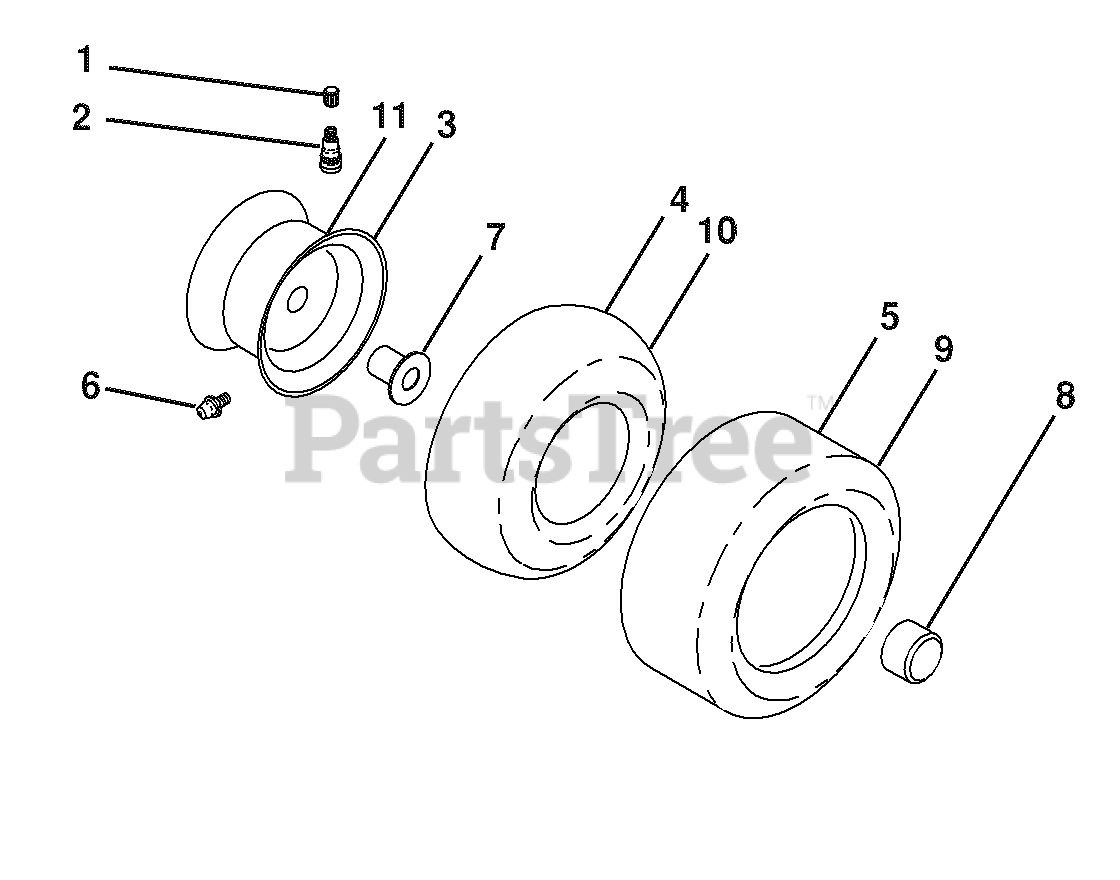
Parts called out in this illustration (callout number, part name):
1	Cap, Valve, Tire
2	Stem, Valve
3	Rim Assembly, Front
4	Tube, Front
5	Tire, Front
6	Fitting, Grease
7	Bearing, Flange
8	Cap, Axle
9	Tire, Rear
10	Tube, Rear
11	Rim Assembly, Rear
11	Sealant, Tire
